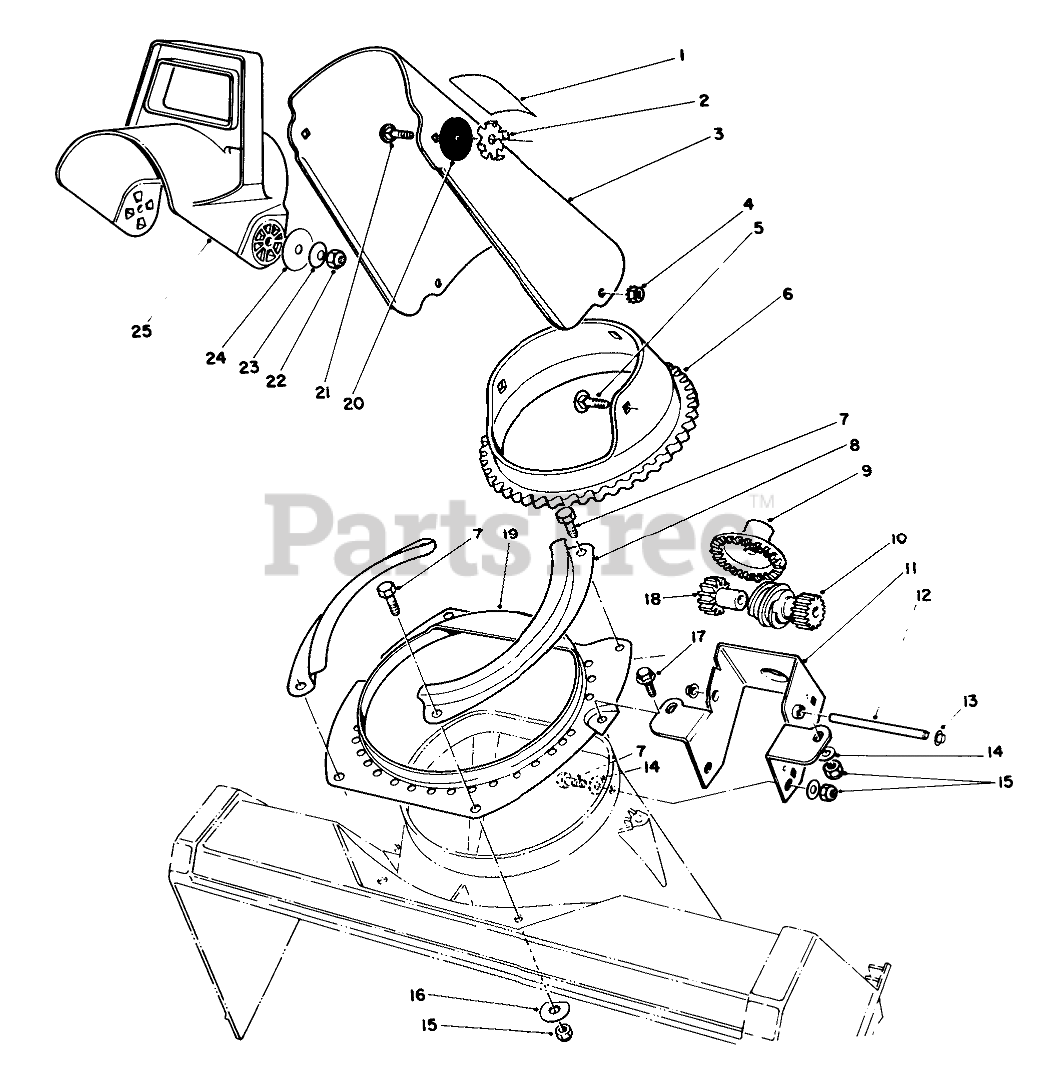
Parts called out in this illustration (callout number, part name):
1	Decal-Danger
2	PLATE-FRICTION
3	Chute-Discharge (Incl. Ref. #1) (Model #38180)
4	NUT-KEPS
5	SCREW-CARR
6	RING-GEAR, CHUTE
7	SCREW-HH
8	Retainer-Chute Ring
9	GEAR-FACE
10	GEAR-SPUR/WORM
11	Bracket-Chute Gears
12	SHAFT-GEAR, WORM
13	NUT-PUSH
14	WASHER-FLAT
15	NUT-LOCK, NI
16	Washer
17	SCREW-PLASTITE
18	GEAR-SPUR, SPACER
19	Ring-Chute Support
20	WASHER-RUBBER
21	SCREW-CARR
22	NUT-LOCK, NI
23	WASHER-BELLEVILLE
24	WASHER-FLAT
25	CHUTE-DEFLECTOR
